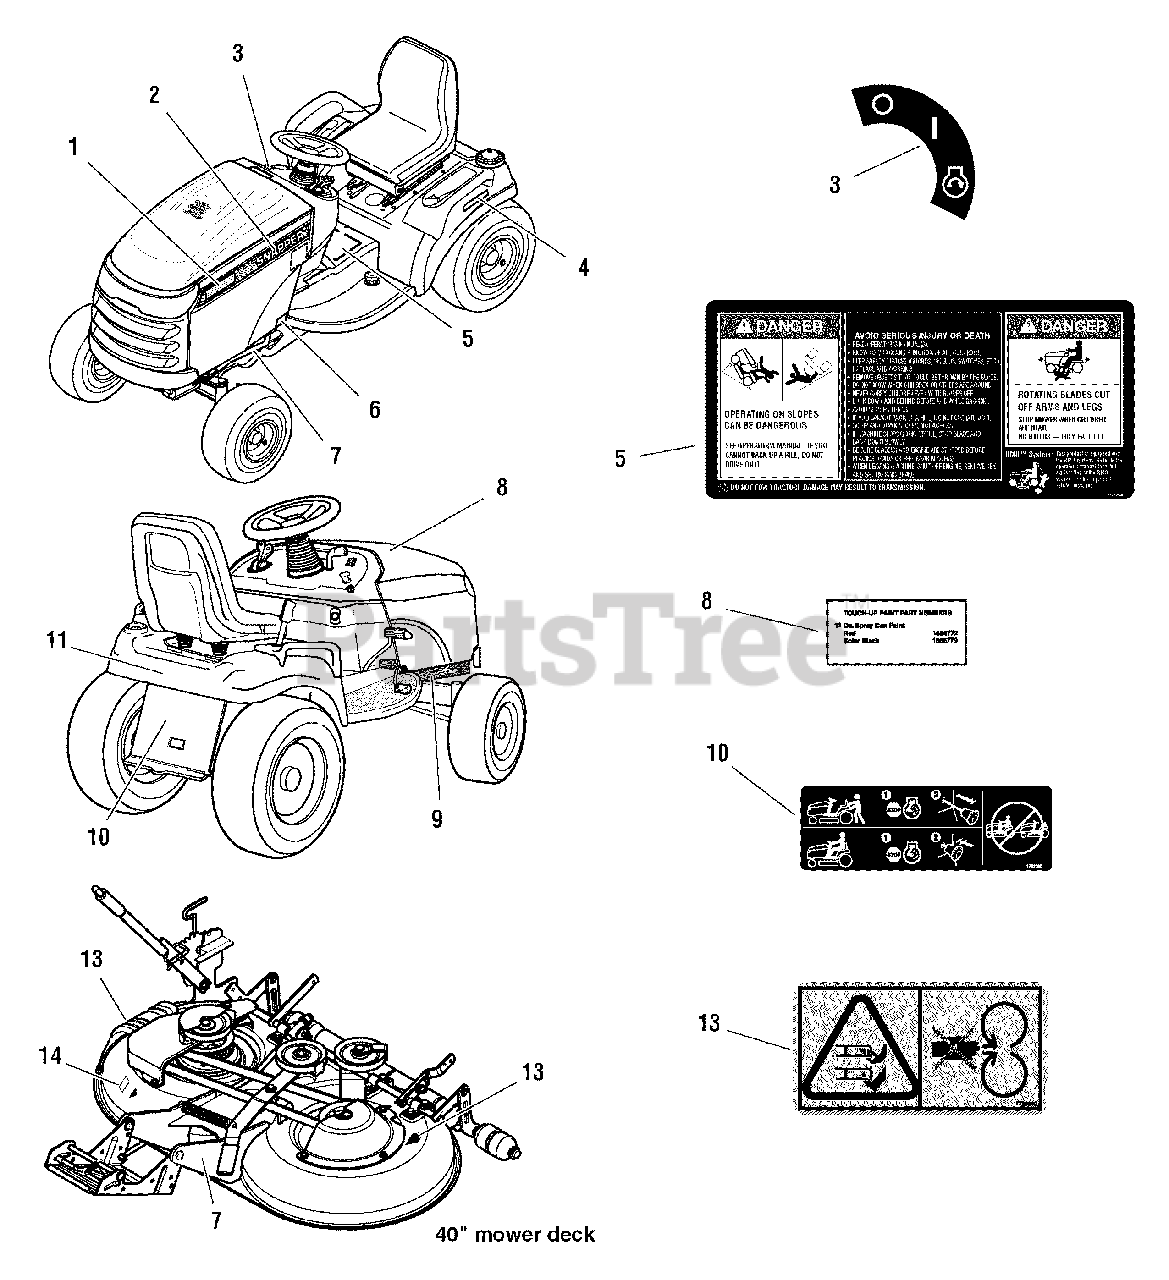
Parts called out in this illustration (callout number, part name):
1	DECAL, LT300-20HP
2	DECAL, Hood Stripe, Snapper, LH
2	DECAL, Hood Stripe, Snapper, RH
3	DECAL, Ignition Switch Symbols, White/Black
4	DECAL, Automatic Control Traction
5	DECAL, Tunnel Cover, Danger Slopes/Blades
6	DECAL, Protective Sticker
7	DECAL, I.D. Plate
8	DECAL, Touch Up Paint
9	DECAL, Patent
10	DECAL, Transmission Release Valve
11	DECAL, Snapper
12	DECAL, OPEI Certified
13	DECAL, Danger Rotating Blades
14	DECAL, 40", Silver on Black with Stripe
